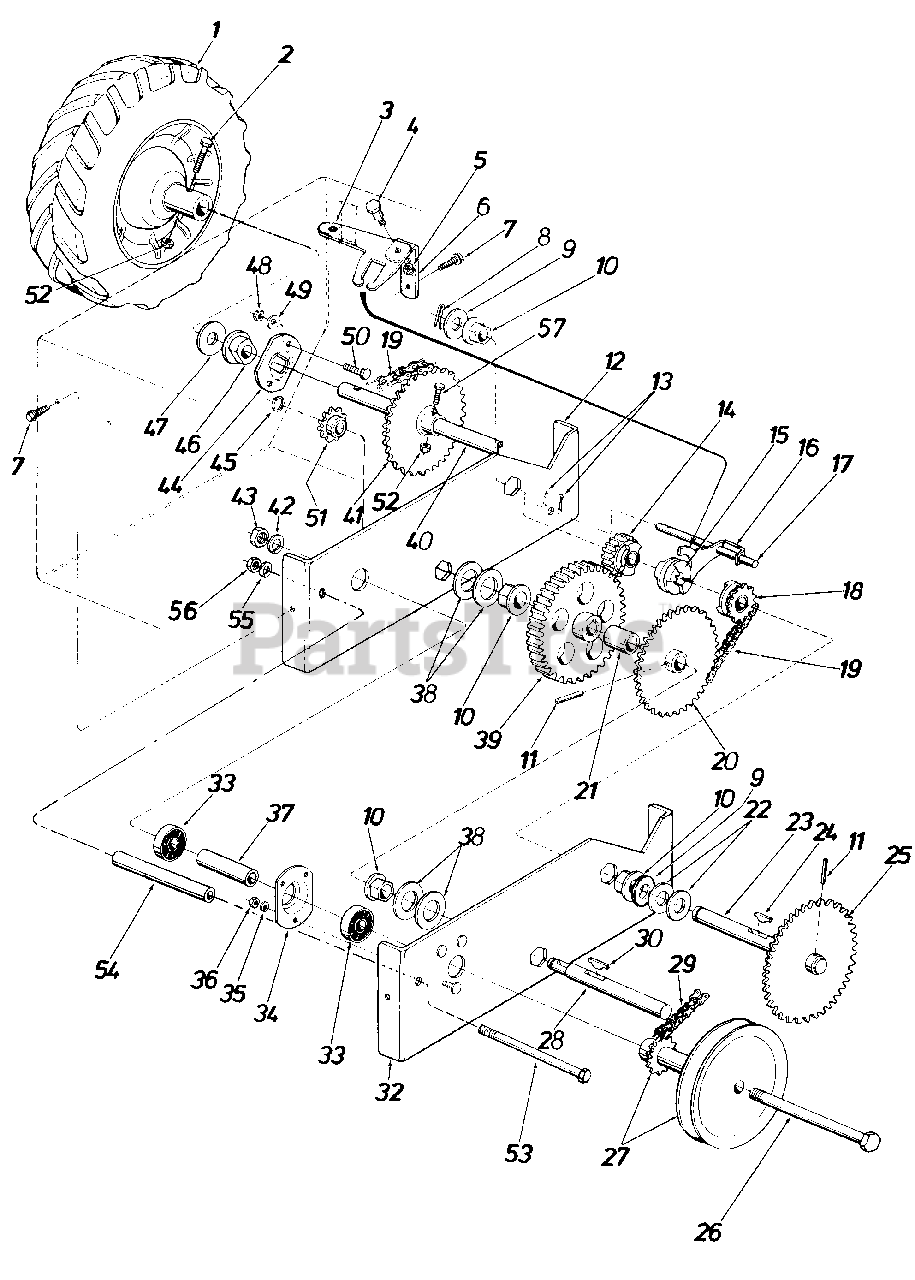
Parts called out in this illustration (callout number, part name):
1	Wheel Ass'y.-Comp. 10 x 2.75-R.H.
2	Hex Bolt 5/16-24 x 1.75" Lg.-H.T.
3	Shifting Bracket
4	Shld. Scr. .438" Dia. x .180 Lg.
5	Hex Ins. L-Nut 5/16-18 Thd.
6	Shifting Bracket Support
7	Hex Wash. Hd. Self-Tap Scr. 5/16-24 x .50
8	Cotter Pin 3/32 Dia. x 1.00" Lg.
9	Fl-Wash. .64 I.D. x 1.25 O.D. x .060
10	Hex Flange Brg. .63 I.D.
11	H-Spring Pin Spiral 1/4" Dia. x 1.50 Lg.
12	Drive Housing Bracket-R.H.
13	Internal Cotter Pin 3/8" Dia.
14	Spur Gear-21 Teeth
15	Clutch Collar
16	Shifting Yoke
18	Sprocket-10 Teeth
19	#41 Chain-1/2" Pitch x 33 Links
20	28 Teeth-Sprocket Hub Ass'y.
21	Spacer-.62 I.D. x .88 O.D. x 1.030
22	Fl-Wash. .64 I.D. x 1.25 O.D. x .100
23	Shifting Shaft
24	Hi-Pro Key 3/16 x 3/4" Dia. x 1.062
25	32 Teeth Sprocket Hub Ass'y.
26	Hex Scr. 1/2-20 x 5.50" Lg.
27	5.25" O.D. Pulley with 9 Teeth Sprocket
28	Shaft
29	#41 Chain 1/2 Pitch x 47 Links
30	Hi-Pro Key-3/16 x 3/4" Dia.
32	Drive Housing Bracket Ass'y.-L. H .
33	Ball Bearing .500 I.D. x 1.38 O.D. x .438
34	Bearing Housing
35	L-Wash. 1/4 Scr.
36	Hex Nut 1/4-20 Thd.
37	Spacer-.52 I.D. x .62 O.D. x 2.69
38	Fl-Wash. 1.06 I.D. x 1.75 O.D. x .100
39	Spur Gear-62 Teeth
40	Wheel Axle
41	28 Teeth-Sprocket Hub Ass'y.
42	L-Wash. 1/2" I.D.
43	Hex Ins. Jam L-Nut 1/2-20 Thd.
44	Bearing Plate
45	External C-Ring
46	Flange Bearing w/Flats .753 I.D.
47	Fl-Wash. .81 I.D. x 1.25 O.D. x .060
48	Hex Nut 5/16-18 Thd.
49	Bell-Wash. 5/16" I.D.
50	Carriage Bolt 5/16-18 x .75" Lg.
51	8 Teeth Sprocket #41 Chain
52	Hex Jam L-Nut 5/16-24 Thd.
53	Hex Bolt 5/16-18 x 4.0" Lg.
54	Spacer 3.25" Lg.
55	L-Wash. 5/16" I.D.
56	Hex Nut 5/16-18 Thd.
57	Hex Bolt 5/16-24 x 1.5" Lg.
